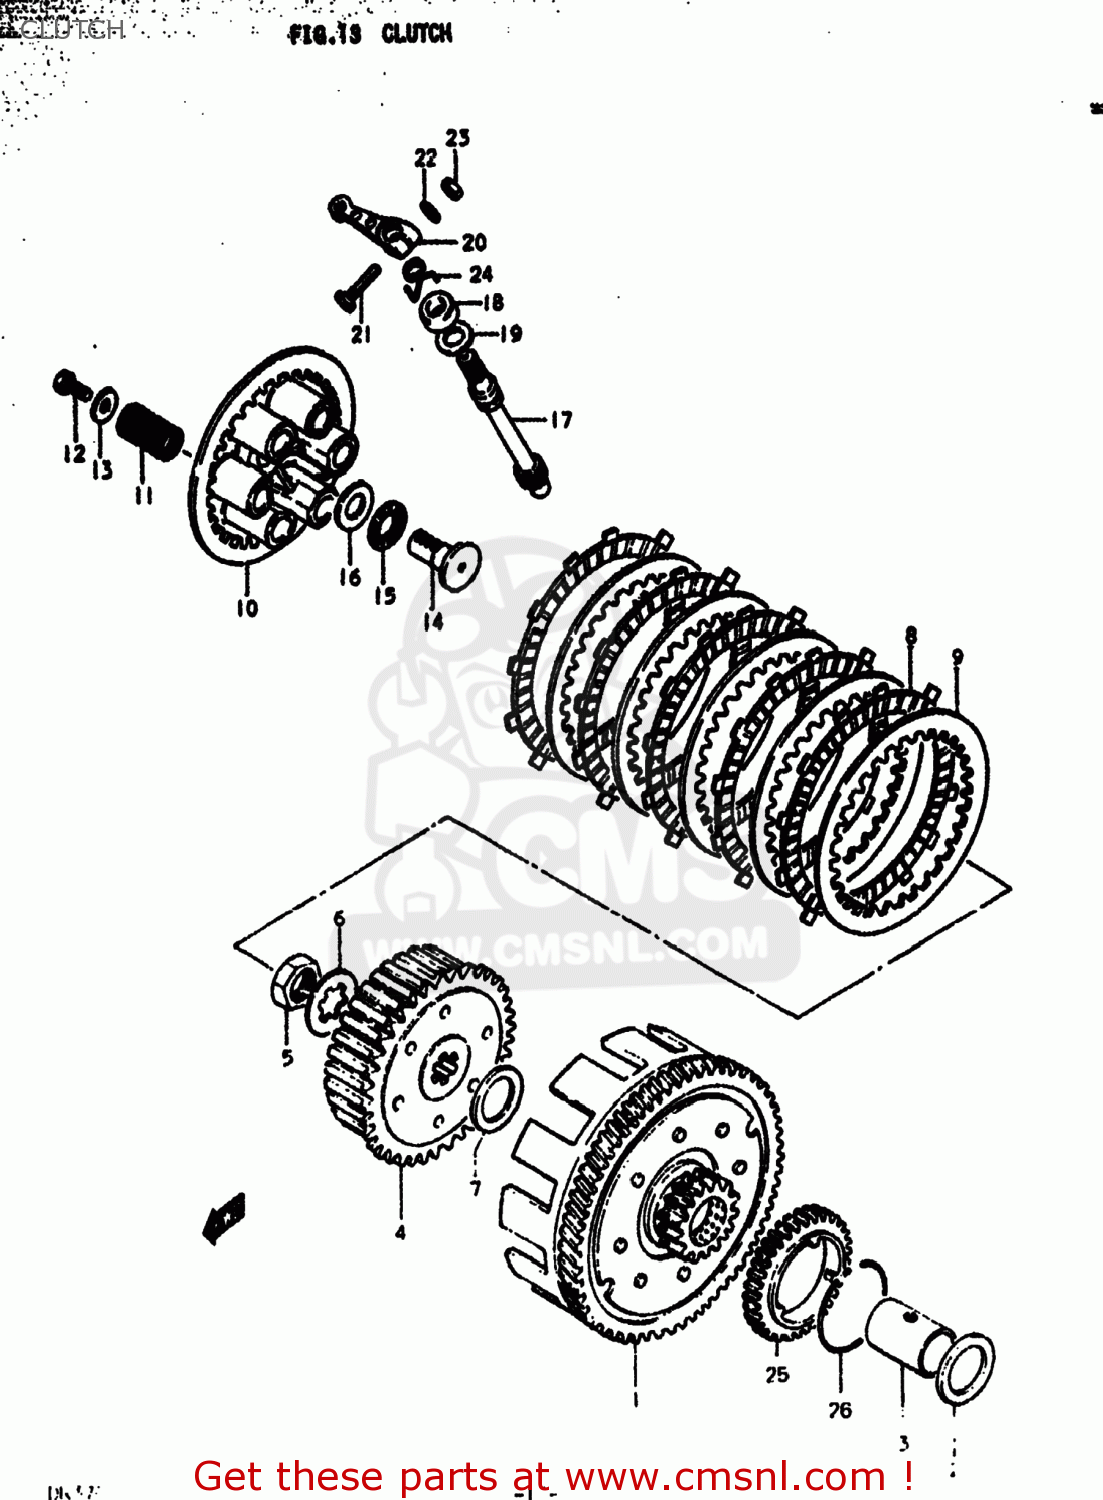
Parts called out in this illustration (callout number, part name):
1	GEAR ASSEMBLY,PRIMARY DRIVE
2	WASHER
3	SPACER
4	HUB,CLUTCH SLEEVE
5	NUT (20MM)
6	WASHER,LOCK
7	WASHER(20X38X2)
8	PLATE,CLUTCH DRIVE (MCA)
9	PLATE,CLUTCH DRIVEN(T:2.0) (NAS)
10	DISC,CLUTCH PRESSURE
11	SPRING
12	BOLT, UPPER
13	WASHER
14	RACK,CLUTCH RELEASE
15	BEARING(15X28X2)
16	WASHER
17	PINION,CLUTCH RELEASE
18	OIL SEAL
19	WASHER (14.2X22X1)
20	ARM,CLUTCH RELEASE
21	BOLT
22	WASHER
23	NUT
24	SPRING
25	GEAR,OIL PUMP DRIVE
26	CIRCLIP
